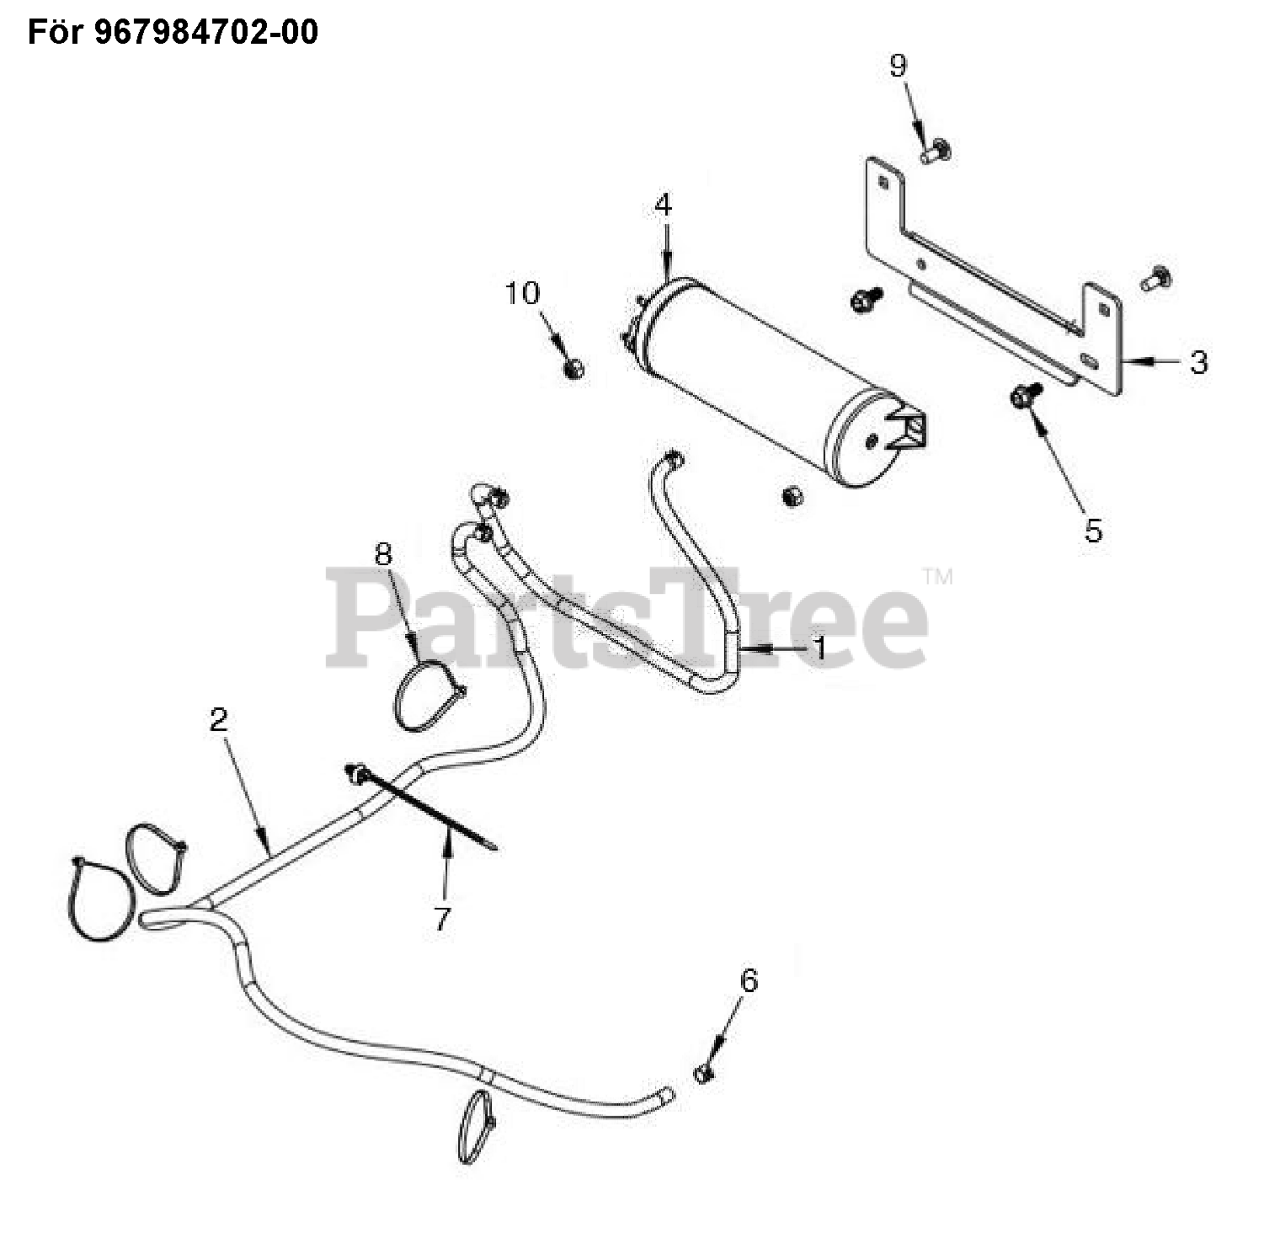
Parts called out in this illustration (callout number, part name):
6	CLAMP, HOSE
7	CABLE.TIE.6".FIRTREE.PZ.REFRES
8	TIE, PLASTIC
9	GSPW Bolts
